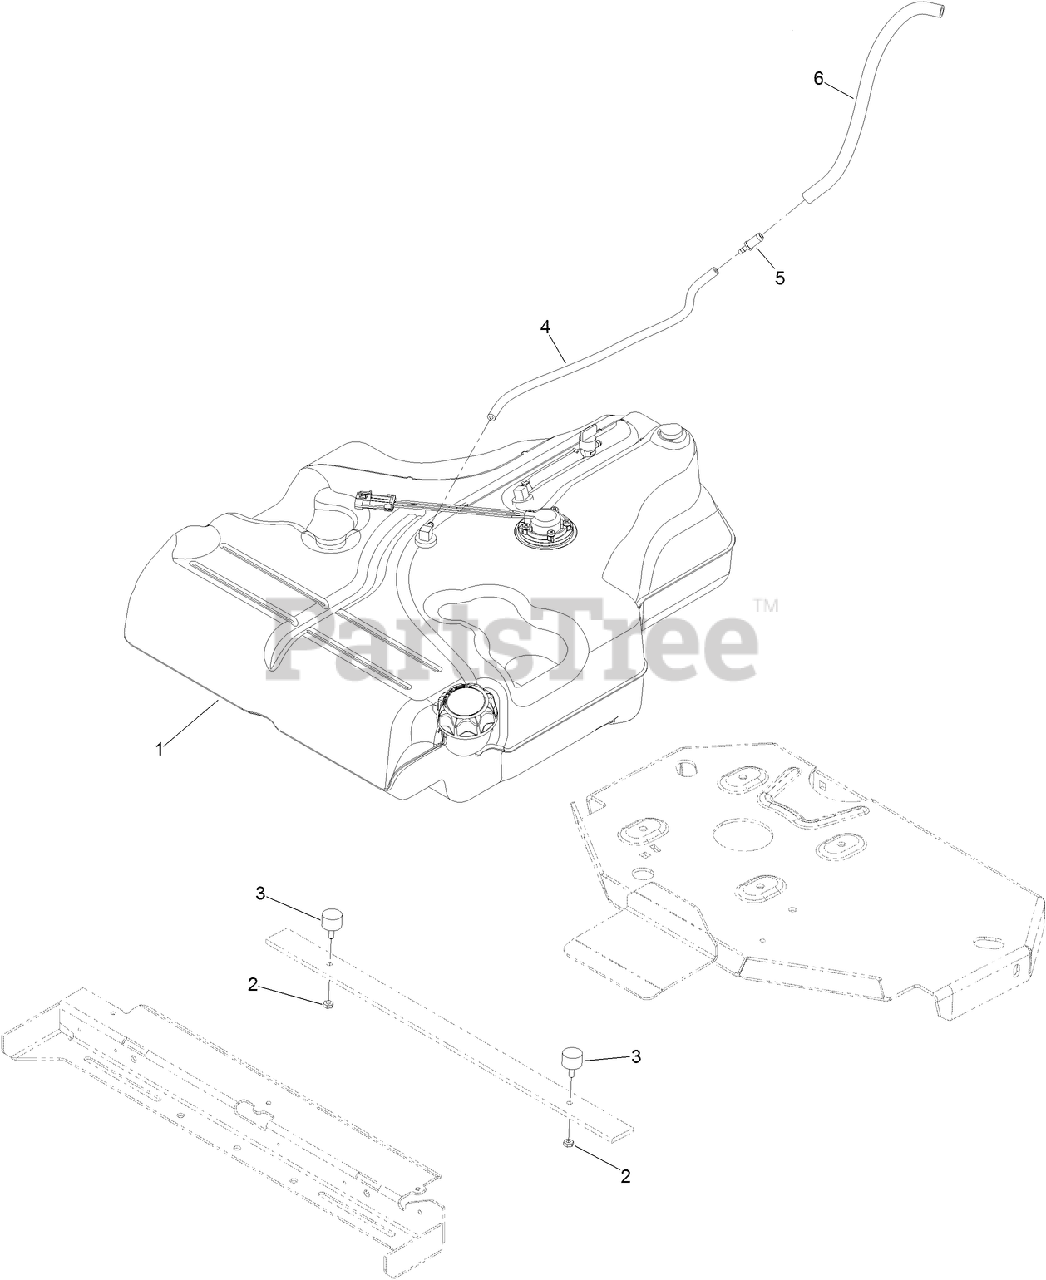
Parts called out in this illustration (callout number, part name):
1	FUEL TANK ASM
2	NUT-JAM
3	BUMPER
4	HOSE-FUEL
5	FITTING-STRAIGHT
6	HOSE-FUEL
